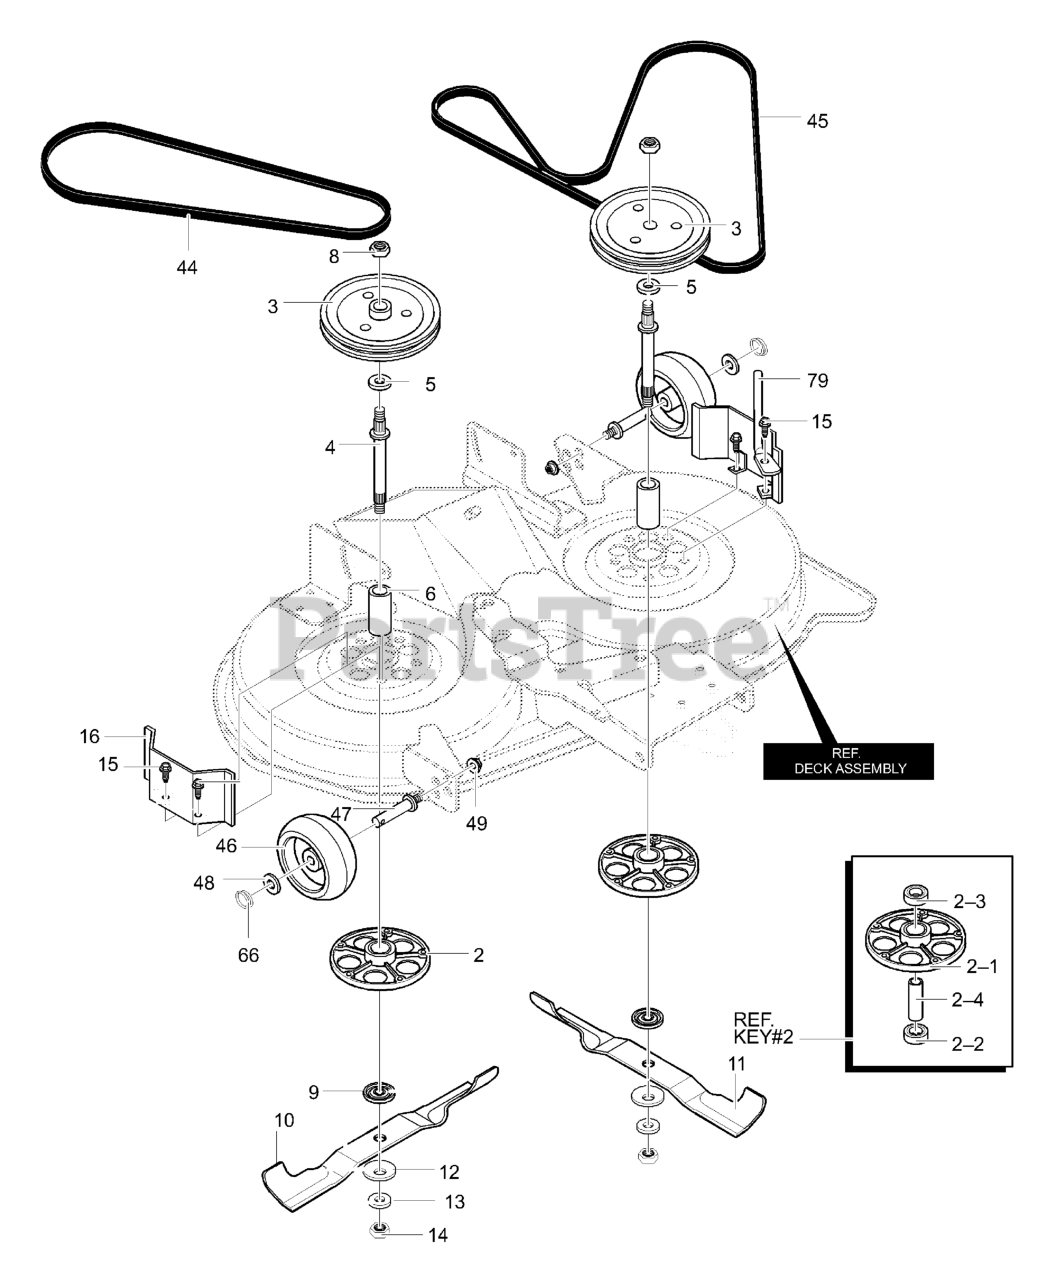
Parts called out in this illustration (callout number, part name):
2	Assembly, Jackshaft Housing
2-1	Housing, Jackshaft
2-2	Bearing, Lower Jackshaft
2-3	Bearing, Upper Jackshaft
3	Pulley, Deck
4	Jackshaft
5	Flatwasher
8	Nut, 9/16-18
9	Adapter, Deck
10	Blade, LH
11	Blade, RH
12	Washer, Bellville
13	Flatwasher
14	Nut, 9/16-18
15	Screw, 3/8-16 x 1.00
16	Pulley Cover
44	Belt, V 46.5LG
45	Belt, Deck
46	Gauge Wheel
47	Shoulder Bolt
48	Flatwasher
49	Nut, 3/8-16
66	Circle Pin
79	Rod, Belt Guide
